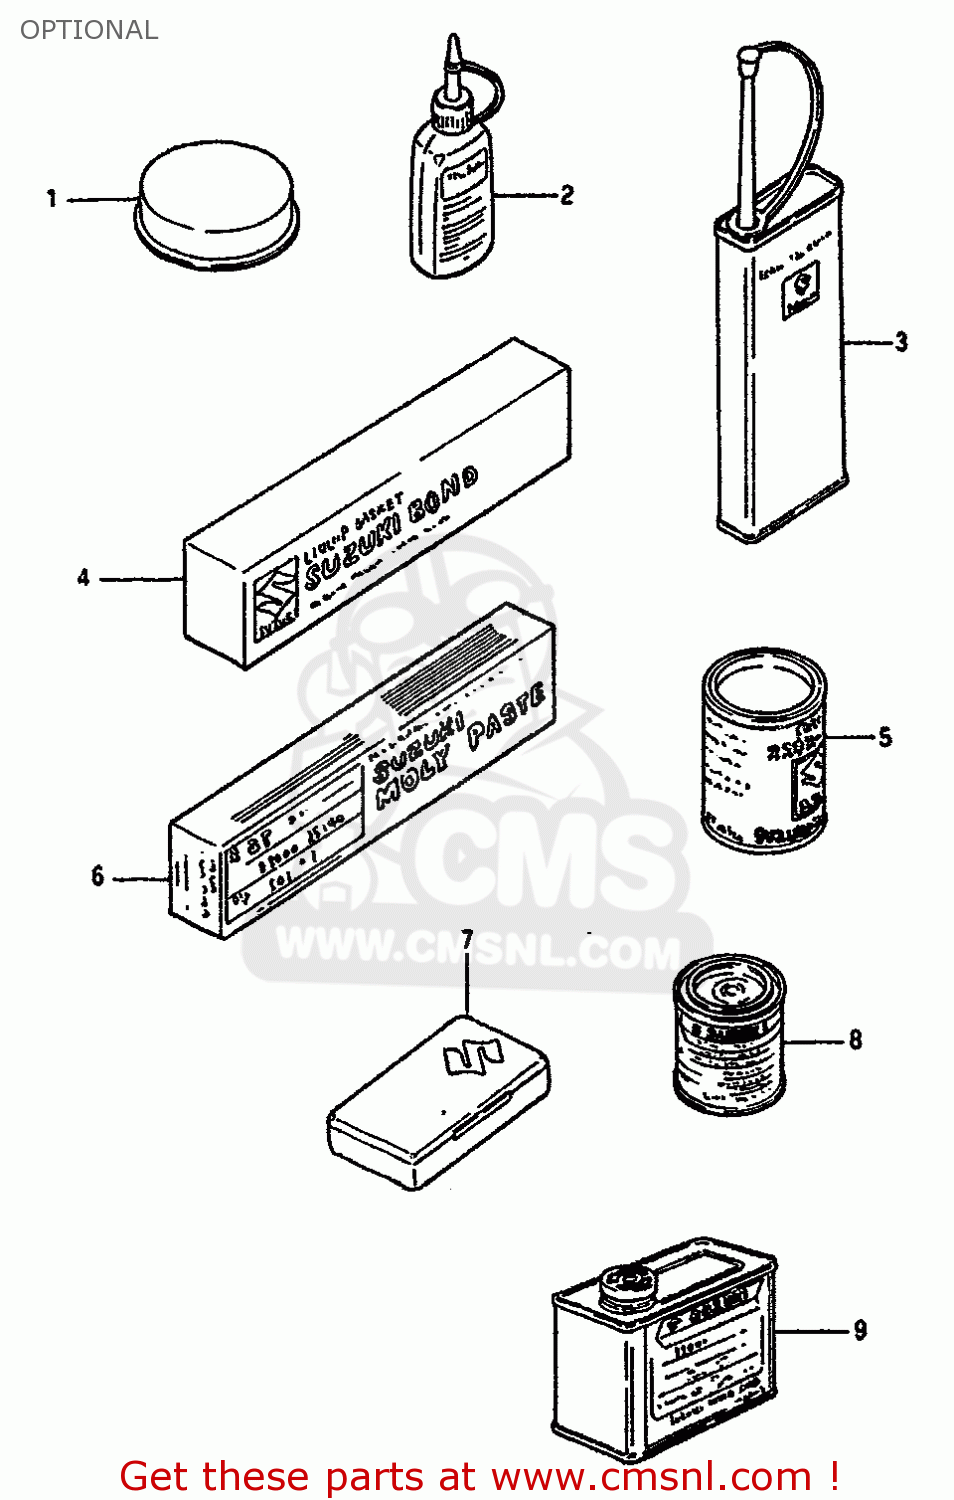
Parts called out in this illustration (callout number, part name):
1	GREASE,PBC FOR BRK PAD 20G
2	THREAD LOCK NO.1342
3	THREAD LOCK NO.1401 CLEAR 200G
4	LIQUID GSKT NO.1215 250G
5	GREASE(C)EP2 LITHIUM 150G
6	SUZUKI MOLY PASTE
7	TUBE REPARING TOOL
8	PAINT,BLACK
9	PAINT (BLACK)
